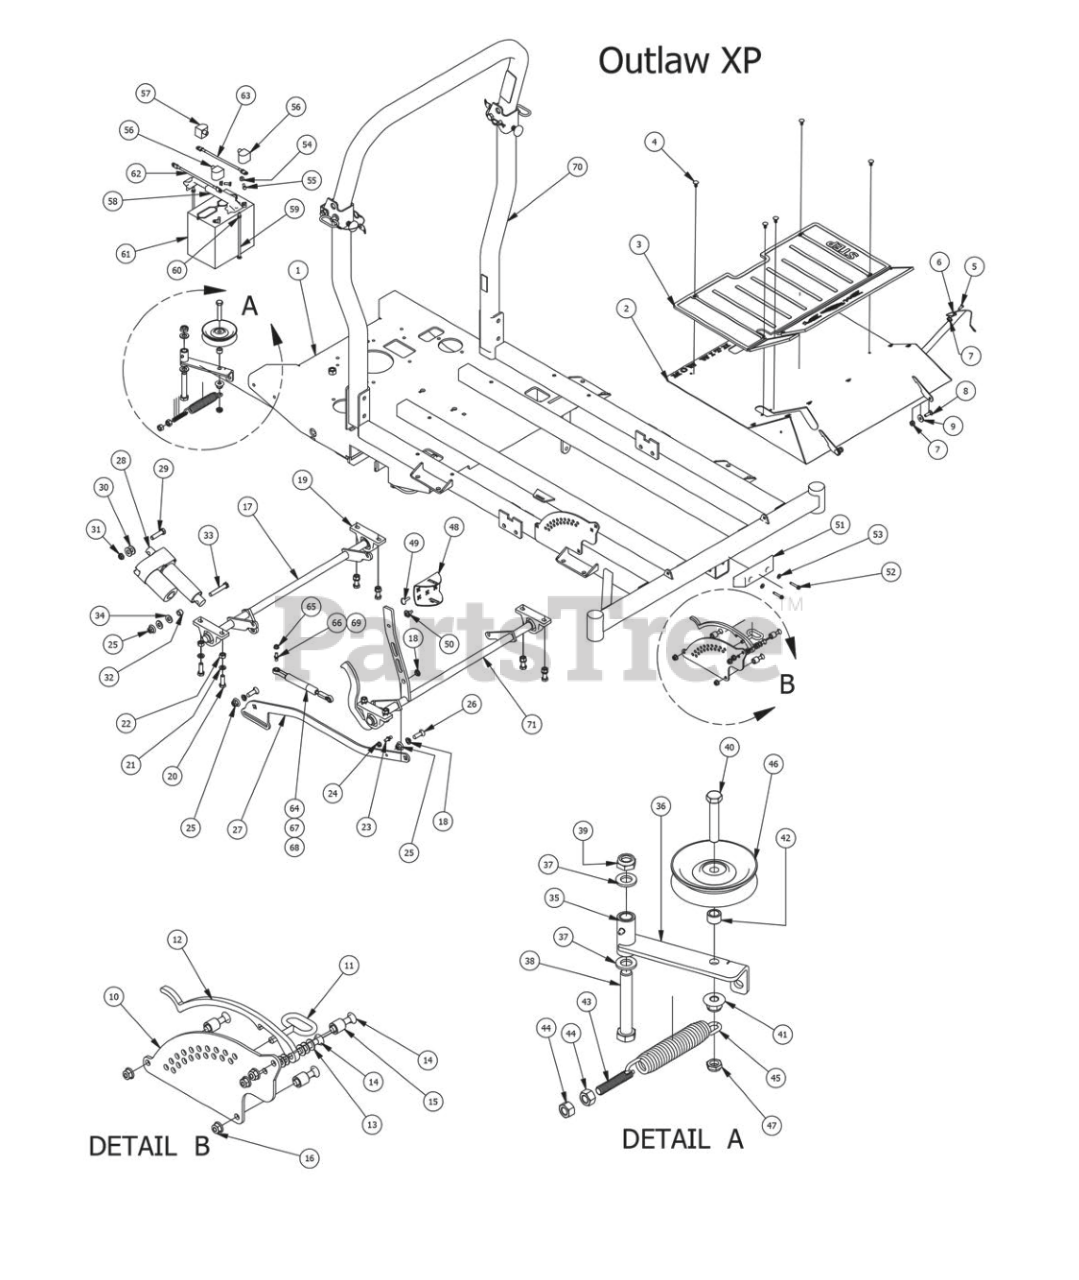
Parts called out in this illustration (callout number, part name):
1	Outlaw XP Frame
2	Outlaw Floor Panel
3	Foot Assist Floor Mat
4	Ratchet Fastener
5	1/4" x 5/8" BS C/S 18-8 SS
6	Floor board Cable W/ Swivel Ends
7	5/16-18 Nylon Flange Nut
8	5/16" x 1" Carriage Bolt
9	.360 ID Plastic Washer
10	Outlaw Height Indicator Plate (Outer)
11	Deck height lever pin
12	Outlaw Deck Lever Lock
13	.390 x .750 x .062 Nylon Washer
14	3/8 x 1 3/4 Carriage Bolt
15	3/4 OD x 1/2 ID x 3\4 Length
16	3/8" Nylock Flange Nut
17	Outlaw Actuator Bar (Rear)
18	Bushing- SF-1620-4
19	pillow block 2bolt sealmaster
20	1/2" x 1 1/2" Hex Bolt
21	1/2" Lock Washer
22	1/2" Hex Nut
23	10mm Damper Ball Stud-Steering
24	5/16" Flange Nut
25	1/2-13 Nylon Flange Nut-Orange
26	1/2 x 1-1/2 Carriage Bolt
27	Outlaw Susp Frame Linkage Bar
29	1/2-13x2 GR 5 Hex Bolt
30	1/2" Washer (Grade 8)
31	1/2" Nylcock Nut (1/2 Jam)
32	1/2 x 1/2 Spacer
33	1/2-13 x GR 5 Hex Bolt Zinc
34	.505 Nylon Spacer
35	Pump Idler assembly Componets 36,40,41,42,46
36	Pump Idler Bracket
37	.635 ID Plastic Washer
38	5/8" x 4" Hex Bolt
39	5/8" Nylock (1/2 Jam)
40	1/2" x 2 3/4" Hex Bolt
41	1/2-13 Nylon Flange Nut-Orange
42	1/2 x 1/2 Spacer
43	All Thread-pump Idler Tensioner
44	1/2" Hex Nut
45	Pump Idler Spring
46	4 3/4" Idler Pulley
47	1/2" Nylcock Nut (1/2 Jam)
48	Outlaw Deck Lift Pedal
49	5/16-18 x1 Thumb Screw Zinc
51	8" Rubber Bumper
52	1/4" x 1 1/2" Self Tapping Screw
53	1/4" Flat Washer
54	1/4-20 Hex Flange Nuts Zinc w/Serrations
55	1/4-20 x 3/4 GR 5 Hex Bolts Zinc
56	Black Boot For ground cable
58	Battery Hold Down
59	1/4-20 X 8 Carriage Bolt
60	1/4-20 Hex Nut
62	Starter to chassis cable
63	Red battery cable
64	200 lb Gas Spring- 54" Deck outlaw
65	5/16" Flange Nut
66	10mm Damper Ball Stud-Steering
67	300 lb Gas Spring 72" Deck Outlaw
68	250 lb Gas Spring 61" Deck outlaw
69	13mm Ball Stud for 72" Deck Only
70	Outlaw-2010 and Up
71	Outlaw Front Actuator Bar Assy
